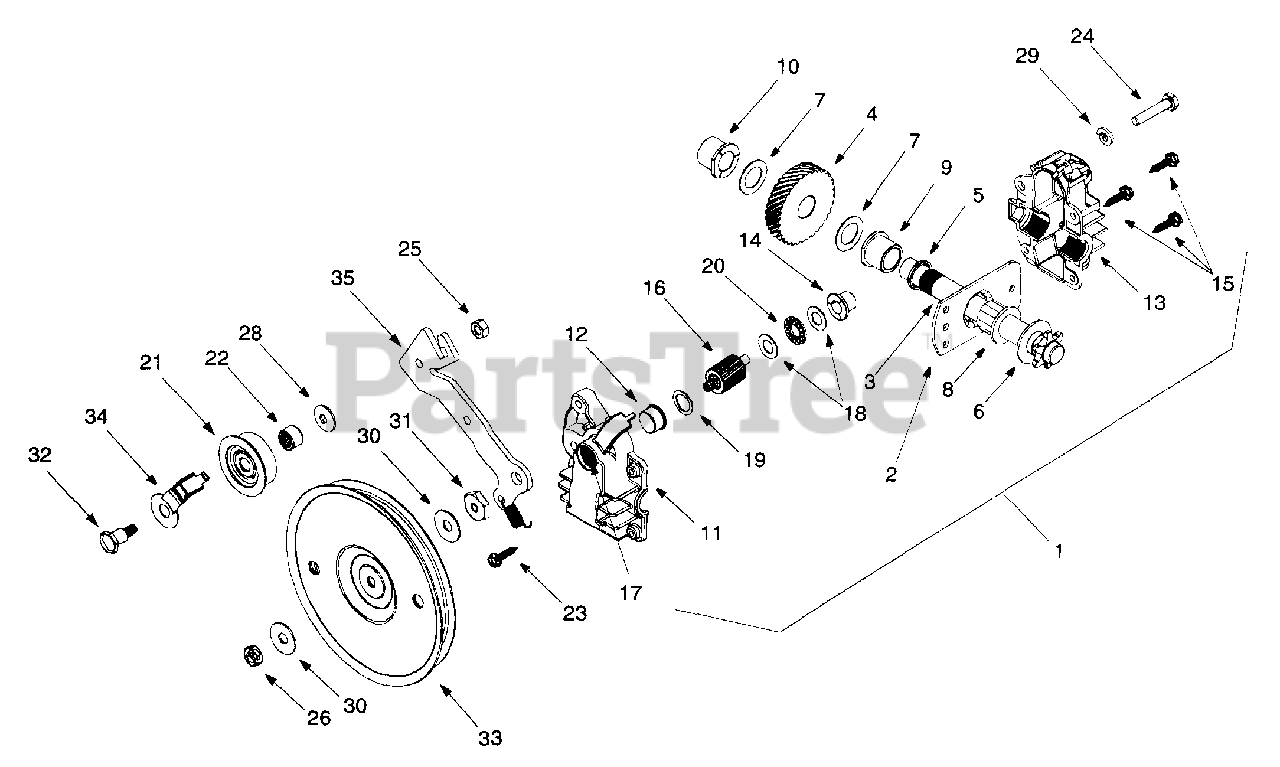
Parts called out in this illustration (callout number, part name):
1	Transmission Assembly, Complete
3	Shaft, Output w/ 6T Sprocket
4	Gear, Helical 34T
5	Seal, Oil, .625 x .812
6	Washer, Flat, .64 x 1.24 x .06 HD
7	Washer, Flat, 5/8 x 1.0
8	Bearing, Hex Flange, .631 ID
9	Bearing, Flange, .629 ID
10	Bearing, Flange, .566 ID
11	Housing, Lower
12	Bearing, Flange, .503 ID
13	Housing, Upper
14	Bearing, Flange, .378 ID
15	Screw, Hex Tapp, #10-16 x .75
16	Shaft, Pinion 10T
17	Seal, Oil, .50 x .687
18	Washer, Thrust, .382 x .684
19	Washer, Flat, .504 x .70 x .030
20	Bearing, Thrust, .375 x .812
21	Pulley Ass'y, Idler w/ Bearing,
22	Bearing, Needle, .375 x .375
23	Screw, Hex Tapp, #10-16 x .75
24	Screw, Hex w/ Patch, 1/4-20 x 1.25
25	Nut, Hex, 1/4-28
26	Nut, Hex Jam, 5/16-24 L.H. Thd
28	Washer, Bell, .265 x.75 x.06
29	Washer, Lock, 1/4
30	Washer, Bell, .325 x .930 x .045
31	Shoulder Spacer, .375 x .165
32	Shoulder Bolt, 1/4-28 x .375
33	Pulley, Flat, 5.06 Dia
34	Belt Keeper
35	Bracket, Idler
